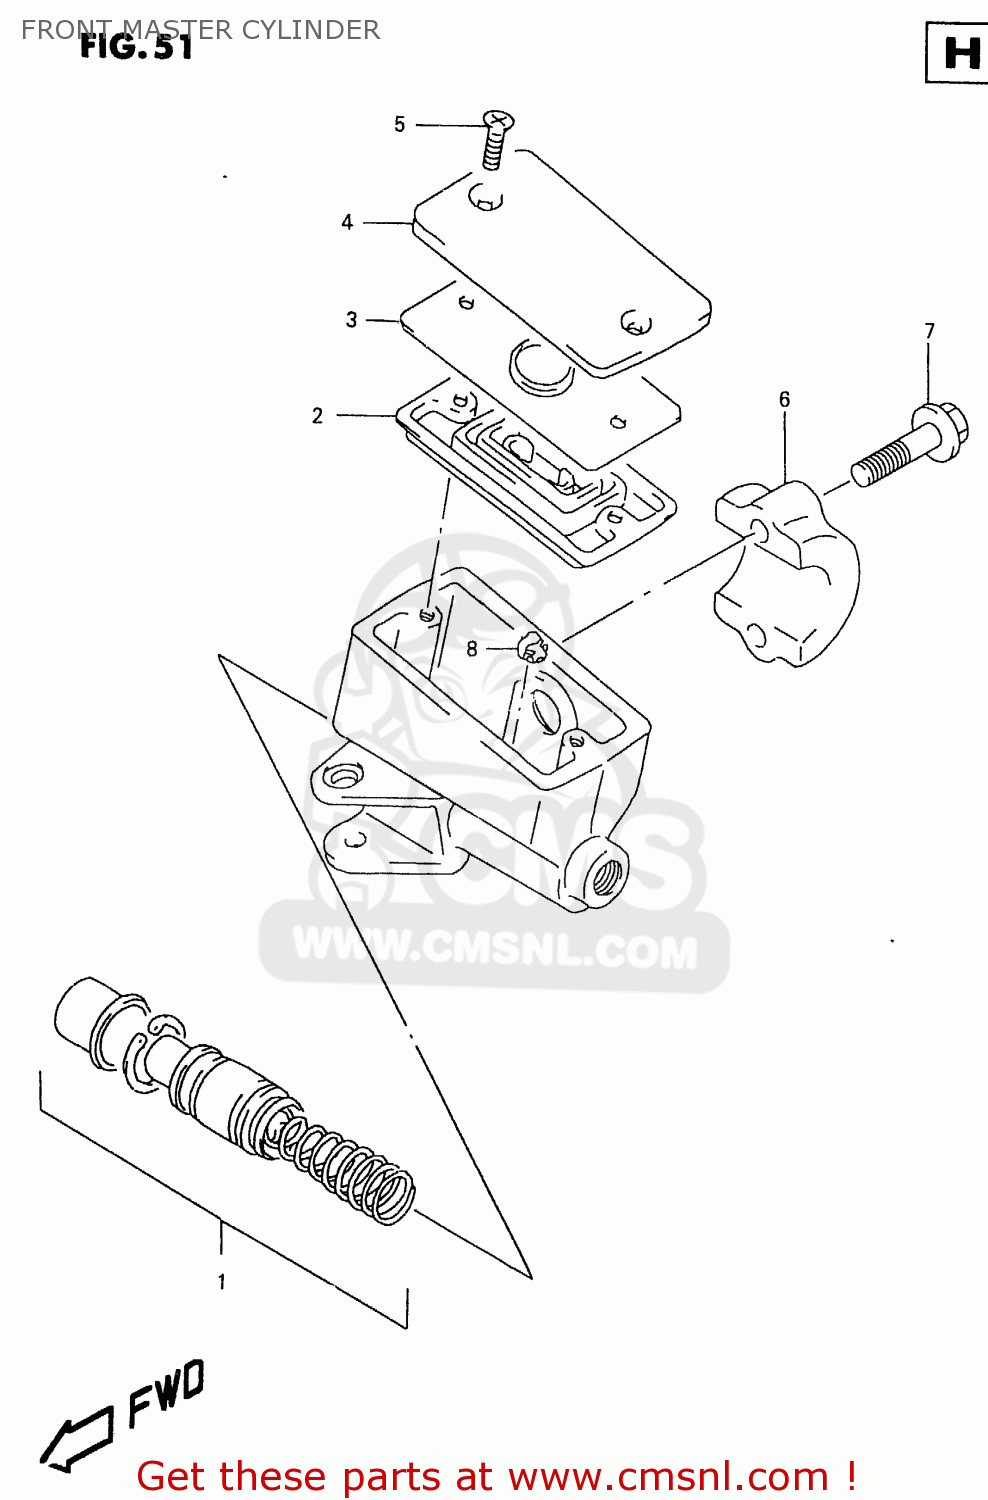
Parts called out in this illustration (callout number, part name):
1	PISTON & CUP SET
2	3
3	PLATE,DIAPHRAGM
4	CAP
5	SCREW
6	HOLDER
7	BOLT(6X25)
8	PROTECTOR
